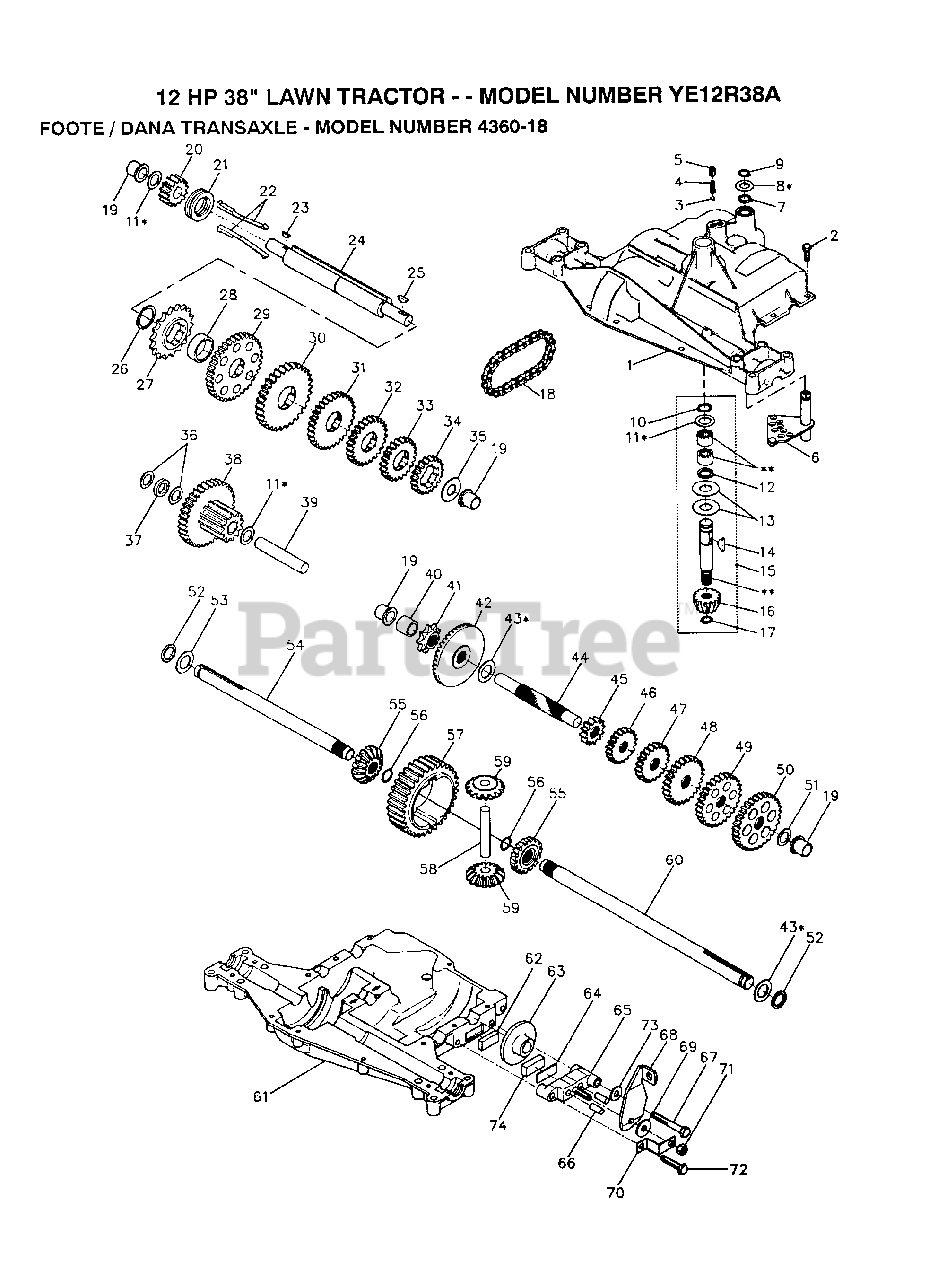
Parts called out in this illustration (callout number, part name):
3	"DETENT, BALL(68003)"
4	"SPRING, DETENT LT"
5	"SCREW, SET LT"
7	ORING T
9	RETAINING RING LT
10	RETAINING RING LT
11	WASHER
12	O-RING T
13	WASHER T
14	WOODRUFF KEY
15	IMPUT KIT T
16	PINION 14T T
17	"RING,RETAINING LT"
18	"CHAIN,24 PTCH LT"
19	BEARING.FLNG.5510
22	KEY T
25	WOODRUFF KEY
26	"RING,RETAINING LT"
27	SPROCKET 18T T
28	SPACER YT
29	KIT.GEAR.12/37TH
32	GEAR 25T LT
33	GEAR SPUR 22 TT
35	"WASHER, PLAIN LT"
36	WASHER 025
37	SPACER
38	ASSM GEAR COMB
39	SHAFT IDLER T
40	SPACER T
41	SPROCKET 9T LT
43	WASHER LT
44	SHAFT T
48	"GEAR, SPUR 25T LT"
49	GEAR 28T T
50	"GEAR, SPUR 31T LT"
51	WASHER 060
53	WASHER 062
55	GEAR 15T T
56	"RING,RETAINING LT"
58	SHAFT T
59	GEAR 1ST T
62	PUCK T
63	BRAKE DISC. T
64	SPACER LT
66	PIN T
67	SCREW T
68	LEVER ACTUATOR
69	WASHER LT
71	NUT.LOCK.5/16-24
72	"SCREW, TAPPING LT"
73	WASHER T
74	PUCK T
